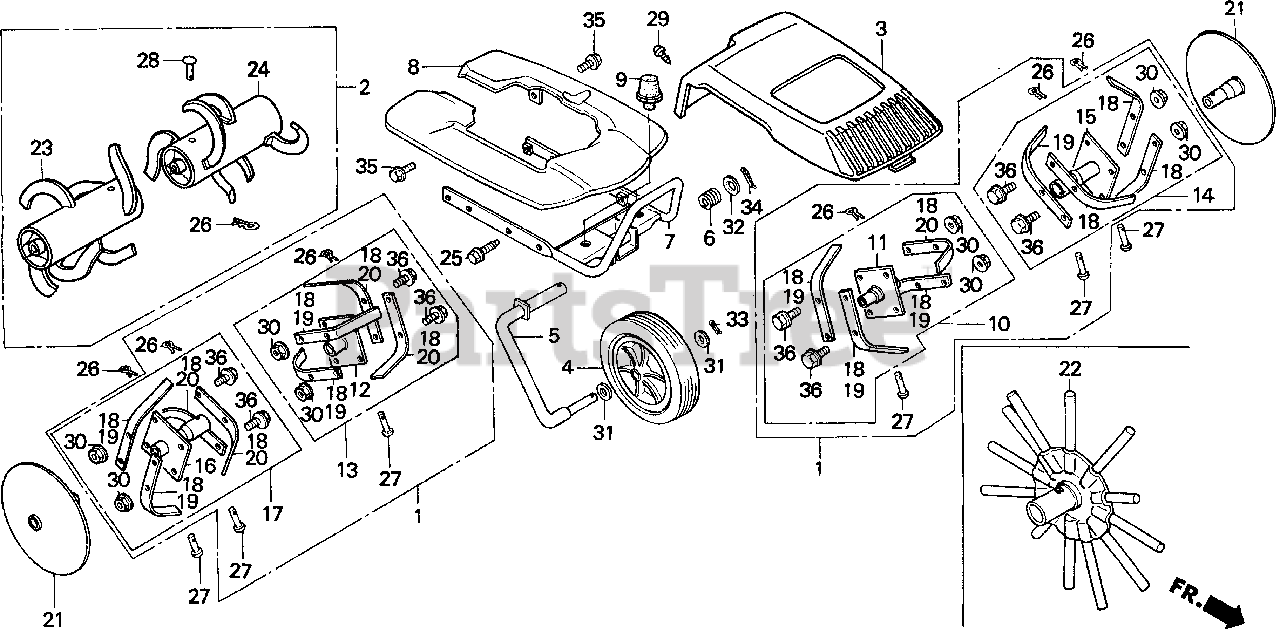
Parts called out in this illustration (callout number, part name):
1	ROTOR KIT *NH1* (BLACK)
2	ROTOR KIT, DRUM (N/A: SEE COMPONENTS)
4	WHEEL (7")
5	BAR, FR. WHEEL
6	SPRING, FR. WHEEL
7	PIPE, FR. GUARD
8	FENDER *NH31* (MCKINLEY WHITE)
9	DAMPER, RUBBER
10	PIPE, L. MAIN *NH1* (BLACK)
11	PIPE, L. ROTOR MAIN
12	PIPE, R. ROTOR MAIN
13	PIPE, R. MAIN *NH1* (BLACK)
14	PIPE, L. EXTENSION *NH1* (BLACK)
14	PIPE, R. EXTENSION *NH1* (BLACK) (NOT AVAILABLE)
15	PIPE, L. ROTOR EXTENSION
16	PIPE, R. ROTOR EXTENSION
17	PIPE, R. EXTENSION *NH1* (BLACK)
18	TINE A, ROTOR
21	DISK, SIDE *NH1* (BLACK)
22	ROTOR, PICK-UP
23	ROTOR, R. DRUM
24	ROTOR, L. DRUM
25	BOLT, FLANGE (6X16)
26	PIN, SNAP (7MM)
27	PIN, WHEEL (8X35)
28	PIN, DRUM ROTOR (8X100)
30	NUT, FLANGE (8MM)
31	WASHER, PLAIN (12MM)
32	WASHER, PLAIN (18MM)
33	PIN, SPLIT (3.0X25)
33	PIN, COTTER (3.0X45)
34	PIN, SPLIT (3.0X25)
34	PIN, COTTER (3.0X45)
35	BOLT, FLANGE (6X12) Use up to Engine SN 1543277.
36	BOLT, FLANGE (8X18) Use from Frame SN 1256673.
